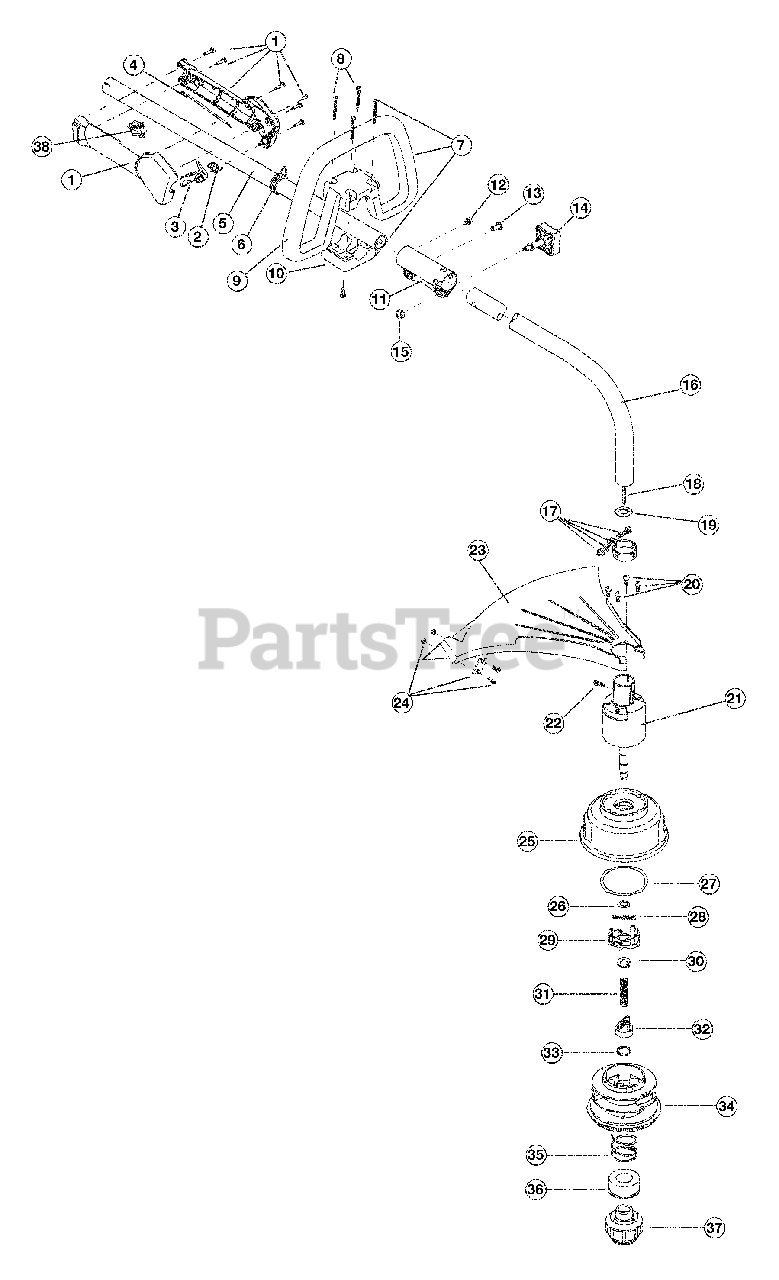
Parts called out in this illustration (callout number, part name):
1	Throttle Housing Assembly
2	Throttle Trigger Spring
3	Throttle Trigger
4	Throttle Cable Assembly
5	Upper Drive Shaft Housing Assembly
6	Harness Clip
7	Deluxe D-Handle Assembly
9	Deluxe D-Handle
10	Bottom Clamp
11	Split Boom Coupler
14	Adjustment Knob
15	Knob Retaining Nut
16	Lower Drive Shaft Housing Assembly
17	Lower Clamp Assembly
18	Lower Flexible Drive Shaft
19	Palnut
20	Shield Mounting Screw
21	Bushing Housing Assembly
22	Anti-Rotation Screw
23	Shield Assembly
24	Blade Assembly
25	Outer Spool Assembly
27	Thrust Washer
28	Small Spring
34	Inner Reel
35	Large Spring
37	Bump Head Knob Assembly
